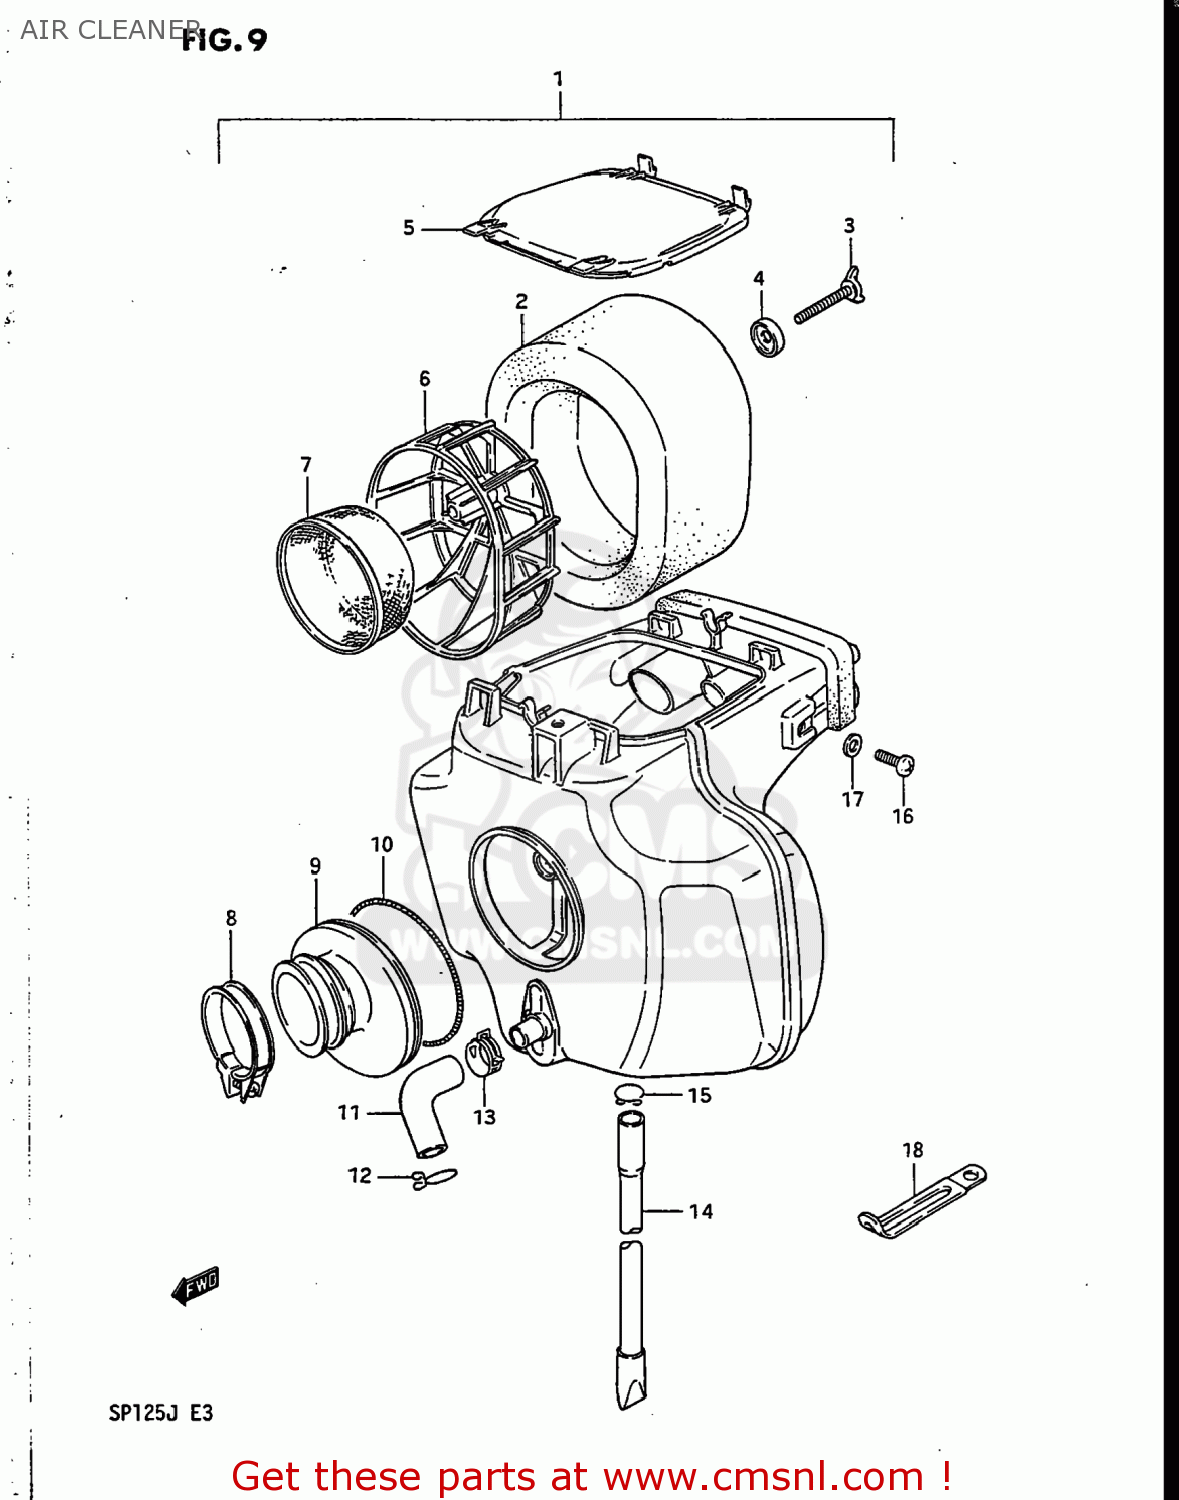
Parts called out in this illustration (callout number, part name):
1	CLEANER ASSEMBLY,AIR
2	FILTER,AIR CLEANER
3	BOLT,WING
4	WASHER,FILTER HOLDER
5	CAP
6	HOLDER,FILTER
7	TRAP
8	CLAMP
9	TUBE,AIR CLEANER OUTLET
10	CLAMP,AIR CLEANER SIDE
11	TUBE,BREATHER
12	CLIP,BREATHER TUBE
13	CLIP
14	DRAIN TUBE
15	CLIP
16	SCREW
17	WASHER,LOCK
18	CLAMP
